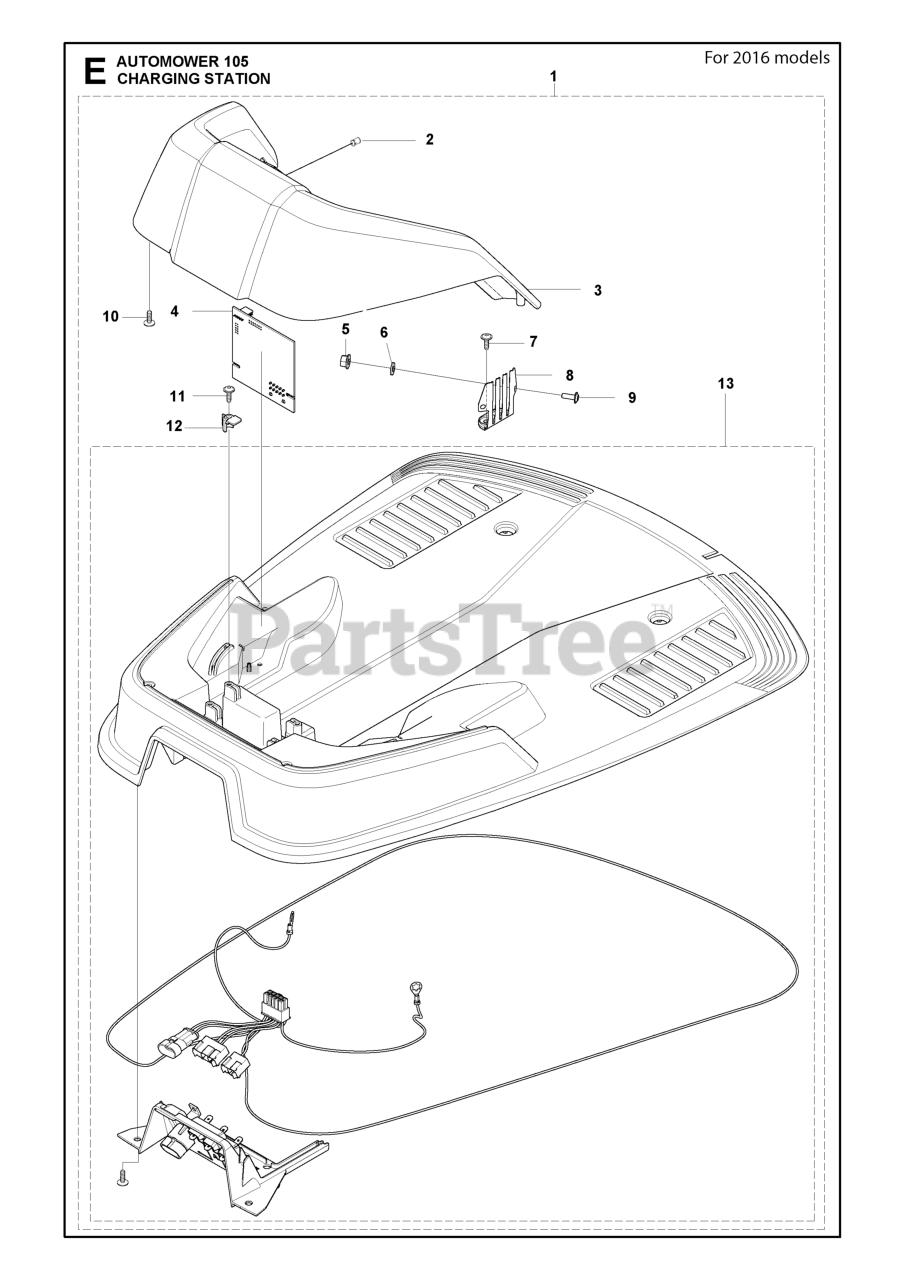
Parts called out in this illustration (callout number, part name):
2	LENS DIODE
5	HEXAGON NUT FLANGE M4 A2-70
6	FIBER WASHER
7	SCREW 14MM
8	CONTACT CHARGER STATION CONTAC
9	SCREW ITXPANM M4X12 A2-70 PAT
10	CABLE ASSY CHARGING STATION
11	SCREW 14MM
12	BRACKET
13	CHARGING STATION BASE PLATE
14	SCREW 14MM
17	SCREW 14MM
18	PANEL ASSY AMP
